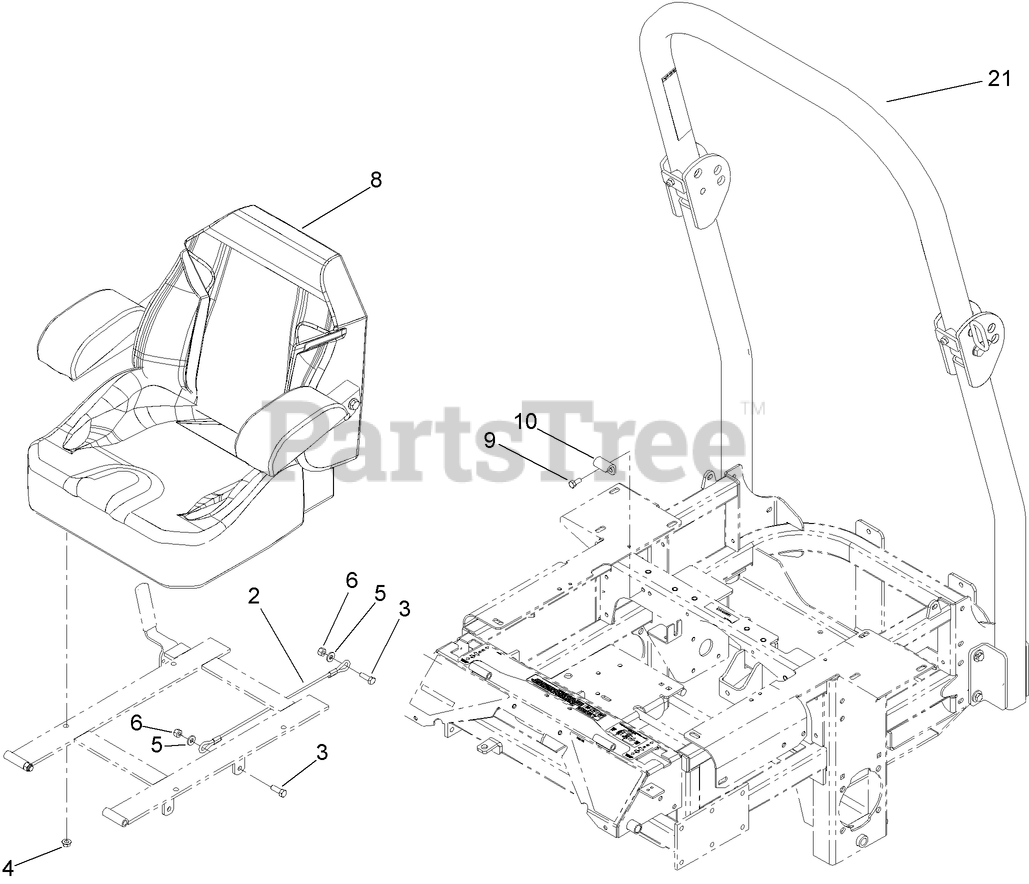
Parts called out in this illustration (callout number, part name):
2	CABLE-SEAT
3	SCREW-HH
4	NUT-HF
5	WASHER
6	NUT-LOCK, NI
8	SEAT-STANDARD
9	SCREW-HH
10	Catch-Latch, Seat
21	ROPS KIT
